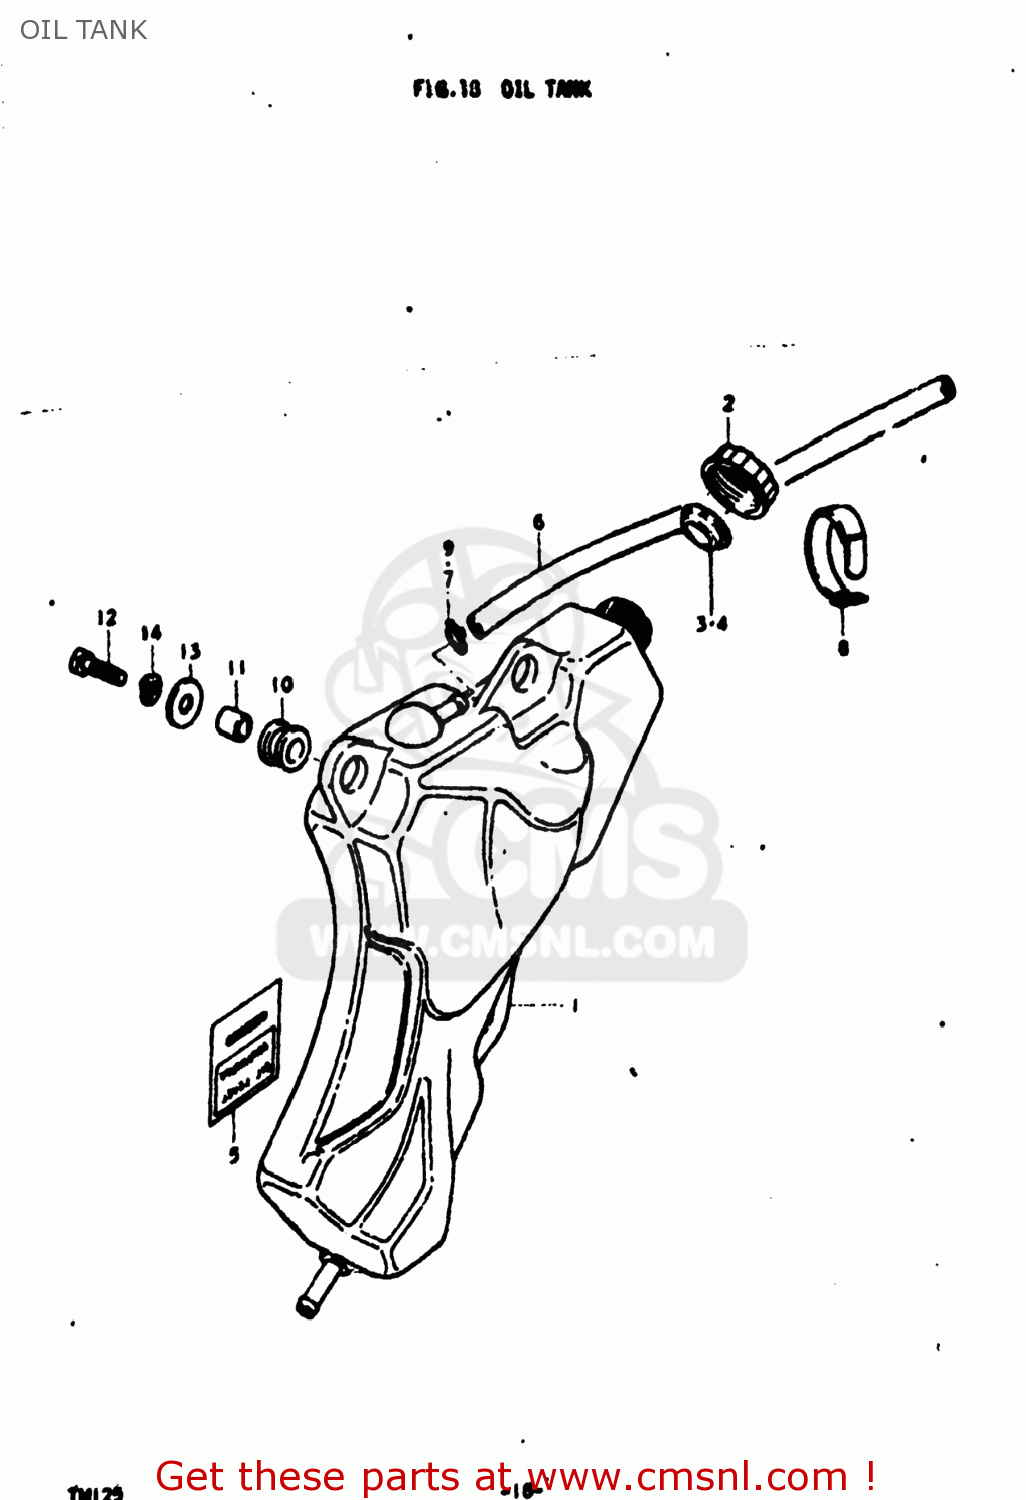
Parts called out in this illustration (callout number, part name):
1	TANK,OIL
2	CAP, OIL TANK
3	GASKET,OIL TANK (NAS)
4	GASKET,OIL TANK (NAS)
5	LABEL
6	HOSE
7	CLIP
8	CLAMP
9	CLIP
10	CUSHION
11	SPACER (6.8X10X10)
12	BOLT
13	WASHER (6.5X20X1.2)
14	LOCK WASHER
